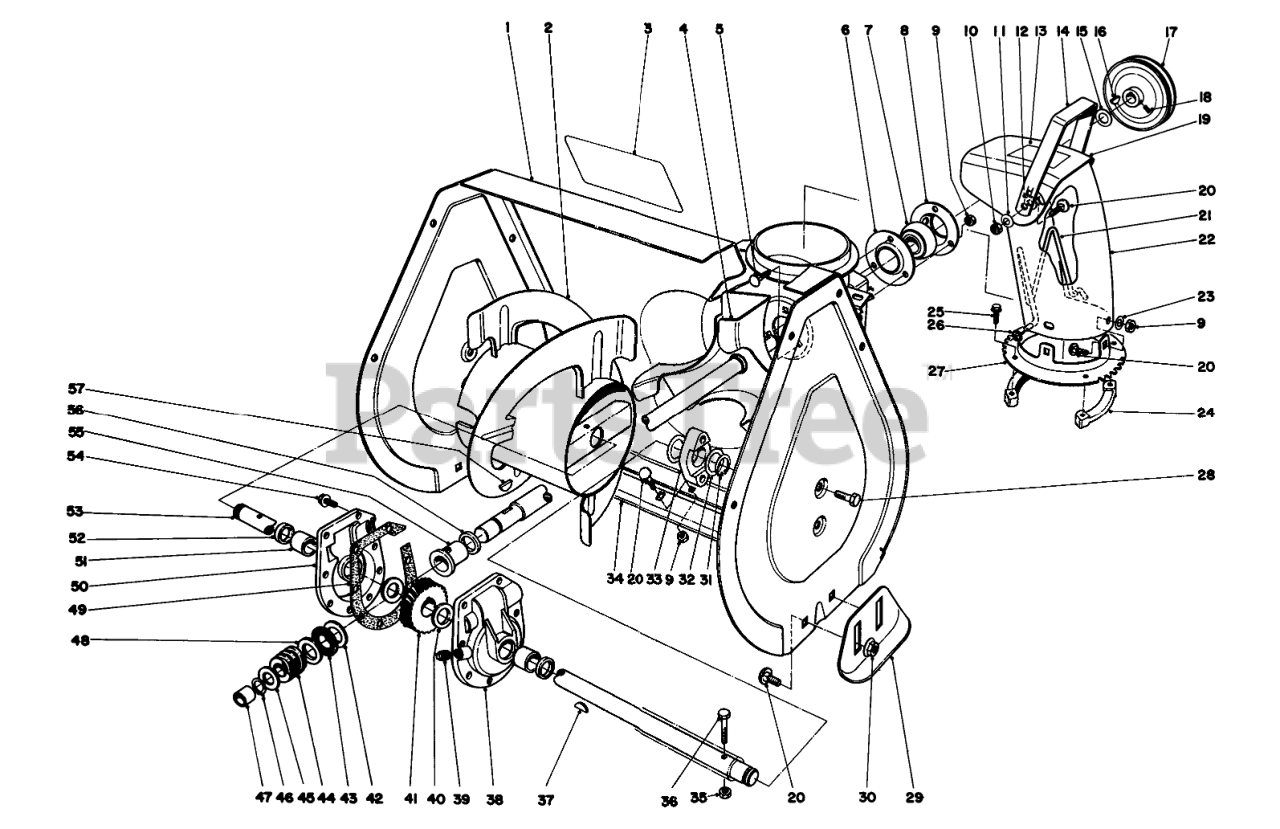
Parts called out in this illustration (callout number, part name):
1	Auger Housing
2	Auger R.H.
3	Decal-Warning
4	Shaft & Impeiler
5	BOLT-CARR
6	FLANGE-CUP, BEARING
7	Ball Bearing
8	FLANGE-CUP, BEARING
9	NUT-LOCK, NI
10	NUT-LOCK, CONE
11	WASHER-BELLEVILLE
12	WASHER-RUBBER
13	Decal-Danger
14	Handle Deflector
15	WASHER
16	KEY-WOODRUFF
17	PULLEY
18	SCREW-SET, SQH
19	Deflector (Incl. Ref. #13)
20	BOLT-CARR
21	CHUTE WIRE
22	DISCHARGE CHUTE
23	WASHER-PLAIN
24	RING-CHUTE, RETAINER
25	SCREW-SPECIAL
26	NUT-PUSH
27	Chute Ring
28	Screw-Self Tapping
29	Skid
30	NUT-HF
31	RING-RETAINING
32	WASHER
33	BEARING-AUGER
34	Blade-Scraper
36	SCREW-HH
37	KEY-WOODRUFF
38	Gear Case L.H. (Incl. Ref. #51 & 52)
39	PLUG-PIPE, SQH
40	WASHER-THRUST
41	Gear
42	WASHER-THRUST
43	BEARING-THRUST
45	WASHER-THRUST
46	Ring-Snap
47	BUSHING
48	WASHER-THRUST
49	GASKET-CASE, GEAR
50	Gear Case R.H. (Incl. Ref. #51 & 52)
51	BUSHING
52	SEAL-OIL
53	AUGER SHAFT
54	SCREW-TAPTITE
55	BUSHING-INPUT
56	RING-QUAD
57	KEY-WOODRUFF
